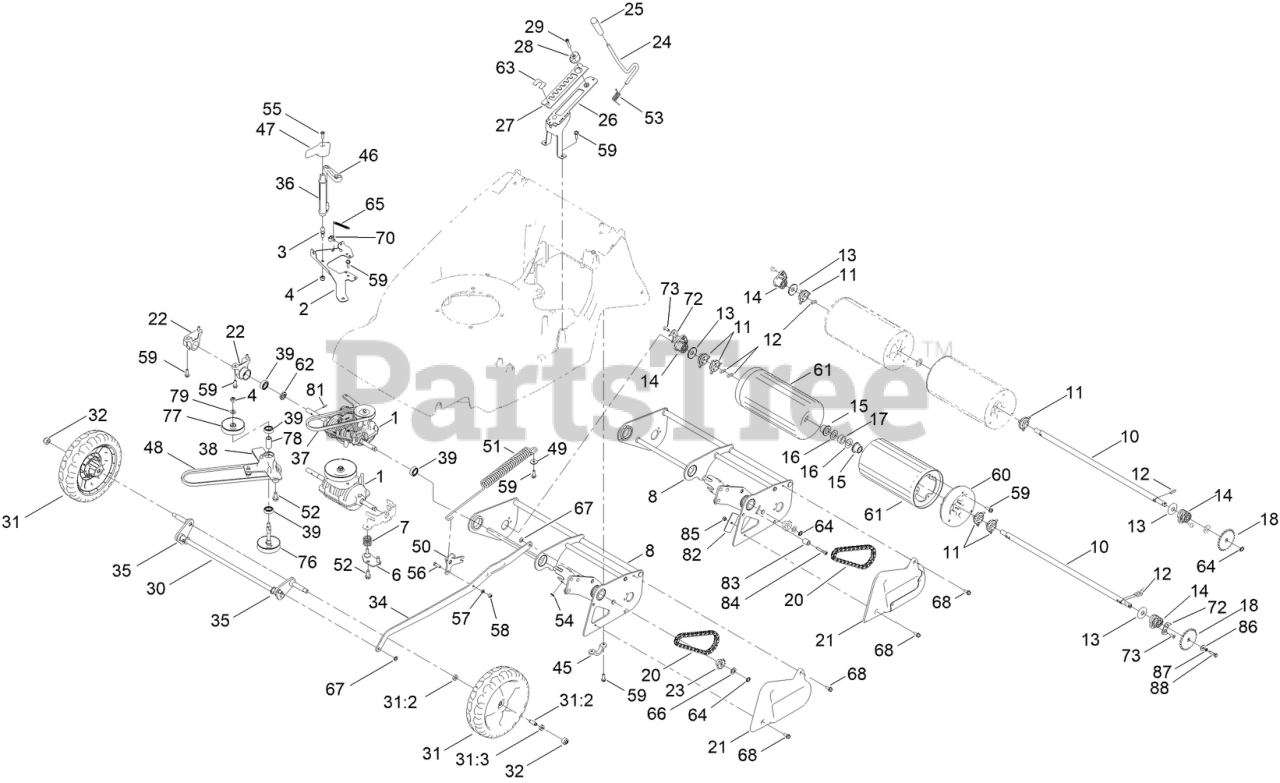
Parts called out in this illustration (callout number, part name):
1	MG510 3-SPEED GEARBOX
2	GEARBOX MOUNTING PLATE
3	STUD-BALL
4	NUT-HEX, NI
6	GEARBOX BRACKET ASSEMBLY
7	SPRING-MOUNTING, GEARBOX
8	REAR FRAME, 56 (PRO)
10	SHAFT-ROLLER, PRO
11	CAM-DRIVE
12	KEY-DRIVE
13	WASHER-THRUST
14	BUSH, REAR ROLLER
15	BUSHING-ROLLER, OILITE
16	WASHER
17	SPACER-ROLLER
18	SPROCKET
20	CHAIN(46 PITCHES 3/8")
21	CHAIN COVER ASM
22	MOUNT-BEARING, FRAME (REAR)
23	SPROCKET, 10T
24	LEVER-HOC
25	KNOB-HOC
26	HOC TOWER ASSEMBLY
27	PLATE-HOC
28	ADJUSTER-HOC
29	SCREW-HSH
30	56 FRONT AXLE ASSEMBLY HD
31:2	BEARING-BALL
31:3	SPACER
32	NUT-HF, NI
34	CONNECTING ROD ASSEMBLY
35	BEARING-AXLE, FRONT
36	ROD-SELECTOR, 3 SPEED
37	V-BELT
38	JACK SHAFT BRACKET
39	BEARING, BALL 12MM
45	AXLE- SUPPORT, REAR
46	ARM-SELECTOR, 3 SPEED
47	KNOB- SELECTOR, 3 SPEED
48	V-BELT
49	WASHER
50	SPRING LOAD LEVER
51	SPRING COUNTER BALANCE
52	SCREW-HWH
53	SPRING-TORSION, HOC
54	GRIP-FIX
55	SCREW
56	SCREW-HH
57	WASHER-PLAIN
58	NUT-NYLOC
59	SCREW-TAPTITE
60	CAP-ROLLER, END
61	ROLLER SHELL ASSEMBLY
62	RETAINING COLLAR, DRIVE SHAFT
63	DECAL-HOC
64	CIRCLIP-EXTERNAL, HD
65	LEVER-SPRING, CLUTCH (RETURN)
66	WASHER-THRUST
67	WASHER-STARLOCK
68	SCREW-TAPTITE
70	CLIP-CONDUIT, TWIN
72	BEARING SUPPORT PLATE
73	SCREW-TAPTITE
76	WELDED JACK SHAFT ASM
77	SPLIT PULLEY UPPER
78	SPACER TUBE, BEARING
79	WASHER-PLAIN
81	PIN, ROLL, 3MM X 16MM
82	BACK PLATE, TENSIONER
83	PULLEY, TENSIONER
85	NUT-NYLOC
86	WASHER-PLAIN
87	WASHER-SPRING
88	BOLT-HH
